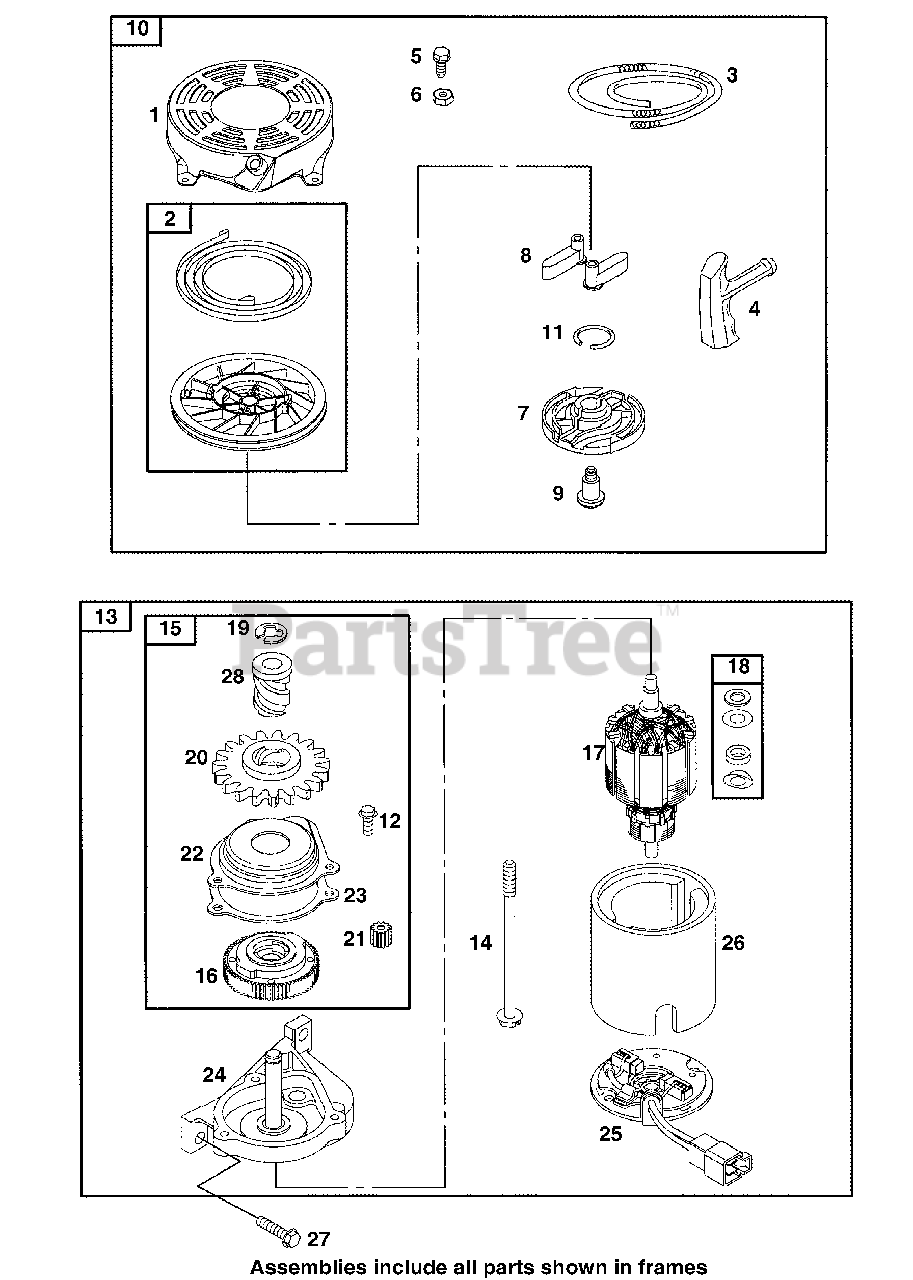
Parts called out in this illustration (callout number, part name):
1	Rewind Starter Housing
2	Starter Pulley
3	Starter Rope
4	Starter Rope Grip
5	Hex Screw
6	Hex Nut
7	Pawl Friction Plate
8	Rachet Pawl
9	Shoulder Screw
10	Rewind Starter
11	Friction Spring
12	Hex Screw
13	Starter Motor
14	Slotted Hex Screw
15	Starter Drive
16	Drive Clutch
17	Starter Armature
18	Shim Set
19	Retainer
20	Pinion Gear
21	Pinion Gear
22	Gear Cover
23	Cover Gasket
24	Drive Cap
25	End Cap
26	Starter Housing
27	Hex Screw
28	Starter Spline
